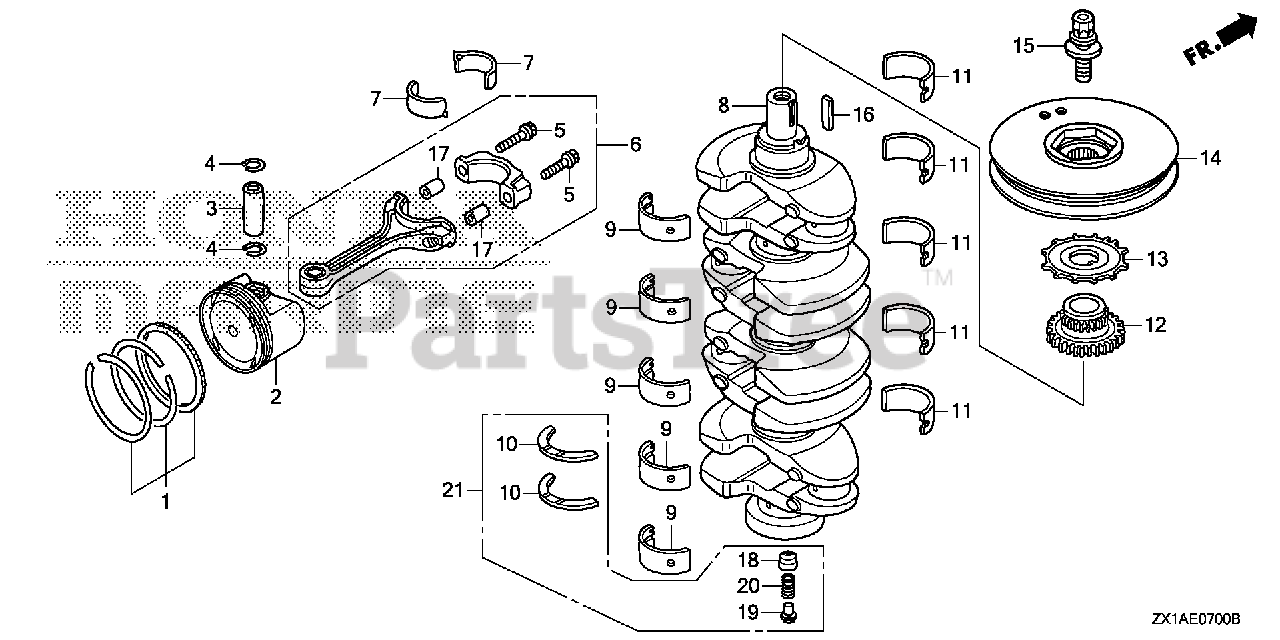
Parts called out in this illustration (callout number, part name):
1	RING SET, PISTON (STD)
3	PIN, PISTON
4	CLIP, PISTON PIN
5	BOLT, CONNECTING ROD
5	BOLT, CONNECTING ROD (SOURCE: VINTAGE PARTS INC.)
6	ROD, CONNECTING
7	BEARING A, CONNECTING ROD (BLUE)
7	BEARING B, CONNECTING ROD (BLACK)
7	BEARING C, CONNECTING ROD (BROWN)
7	BEARING D, CONNECTING ROD (GREEN)
7	BEARING E, CONNECTING ROD (YELLOW)
7	BEARING F, CONNECTING ROD (PINK)
7	BEARING G, CONNECTING ROD (RED)
8	CRANKSHAFT
9	BEARING A, MAIN (UPPER) (BLUE) (DAIDO)
9	BEARING B, MAIN (UPPER) (BLACK) (DAIDO)
9	BEARING C, MAIN (UPPER) (BROWN) (DAIDO)
9	BEARING D, MAIN (UPPER) (GREEN) (DAIDO)
9	BEARING E, MAIN (UPPER) (YELLOW) (DAIDO)
9	BEARING F, MAIN (UPPER) (PINK) (DAIDO)
10	WASHER, THRUST (TAIHO)
10	WASHER, THRUST
11	BEARING A, MAIN (LOWER) (BLUE) (DAIDO)
11	BEARING B, MAIN (LOWER) (BLACK) (DAIDO)
11	BEARING C, MAIN (LOWER) (BROWN) (DAIDO)
11	BEARING D, MAIN (LOWER) (GREEN) (DAIDO)
11	BEARING E, MAIN (LOWER) (YELLOW) (DAIDO)
11	BEARING F, MAIN (LOWER) (PINK) (DAIDO)
12	SPROCKET, CHAIN DRIVE
13	PLATE, CRANK PULSER
14	PULLEY, CRANKSHAFT
15	BOLT-WASHER (16X49)
16	KEY (4.5X21)
17	PIN, DOWEL (10X12)
18	RETAINER, SPRING
19	SEAT, SPRING (150)
20	SPRING, SUPPORT
21	WASHER KIT, THRUST (150)
